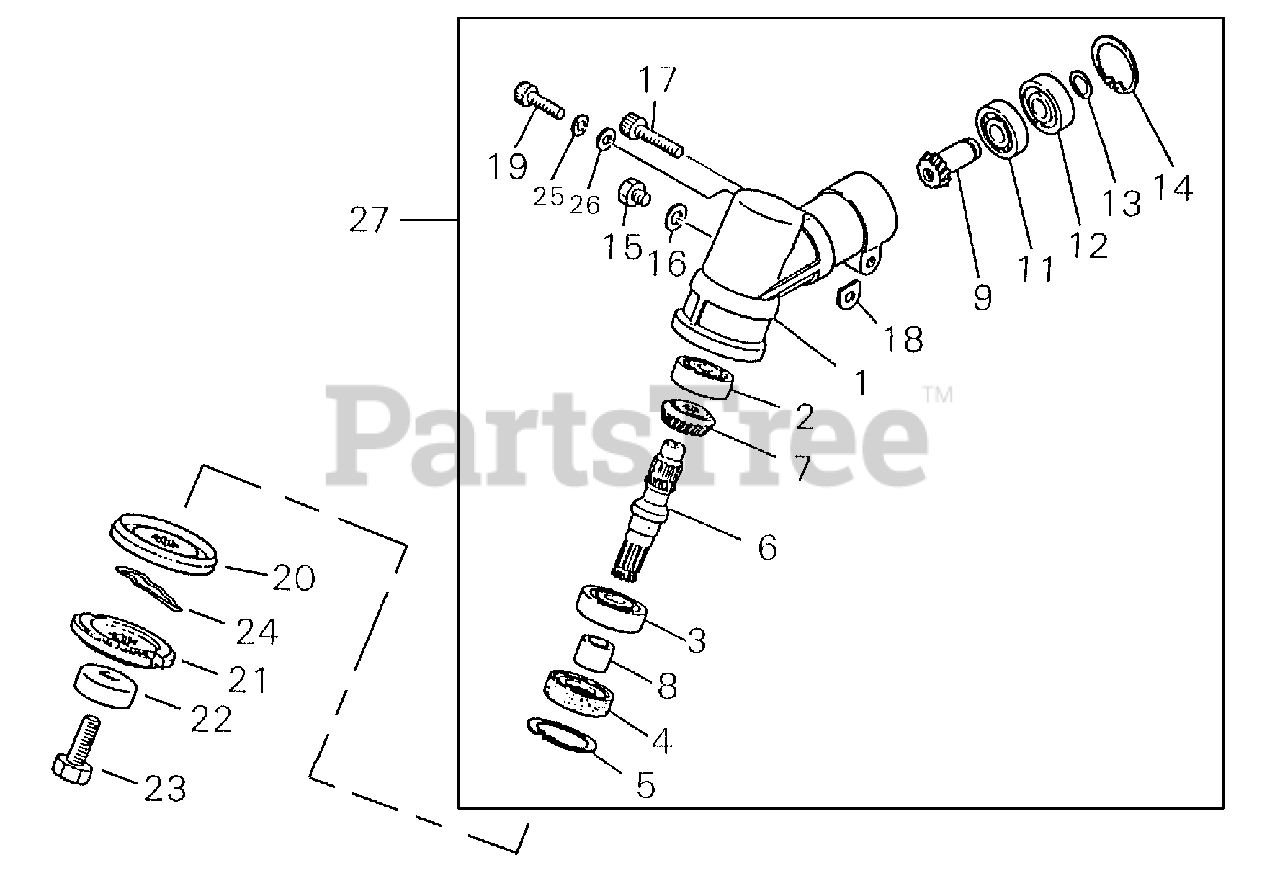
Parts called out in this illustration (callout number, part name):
1	HOUSING, GEAR CASE
2	BEARING, BALL 6000DDU
3	BEARING, BALL 6201
4	SEAL, OIL
5	RING, SNAP Ø32
6	SHAFT, GEAR
7	GEAR, BEVEL
8	SPACER
9	PINION ASSY, BEVEL
11	BEARING, BALL 6000
12	BEARING, BALL 6000ZZ
13	RING, SNAP WR10
14	RING, SNAP Ø26
15	BOLT M6×10
16	WASHER
17	BOLT M6×28
18	D-WASHER
19	BOLT 5×12
20	HOLDER
21	PLATE, ADAPTOR - LOWER
22	GUARD, BOLT
23	BOLT 8
24	CLIP, BLADE
25	WASHER, SPRING 5
26	WASHER, FLAT 5.5×10×0.8
27	GEAR CASE ASSY
